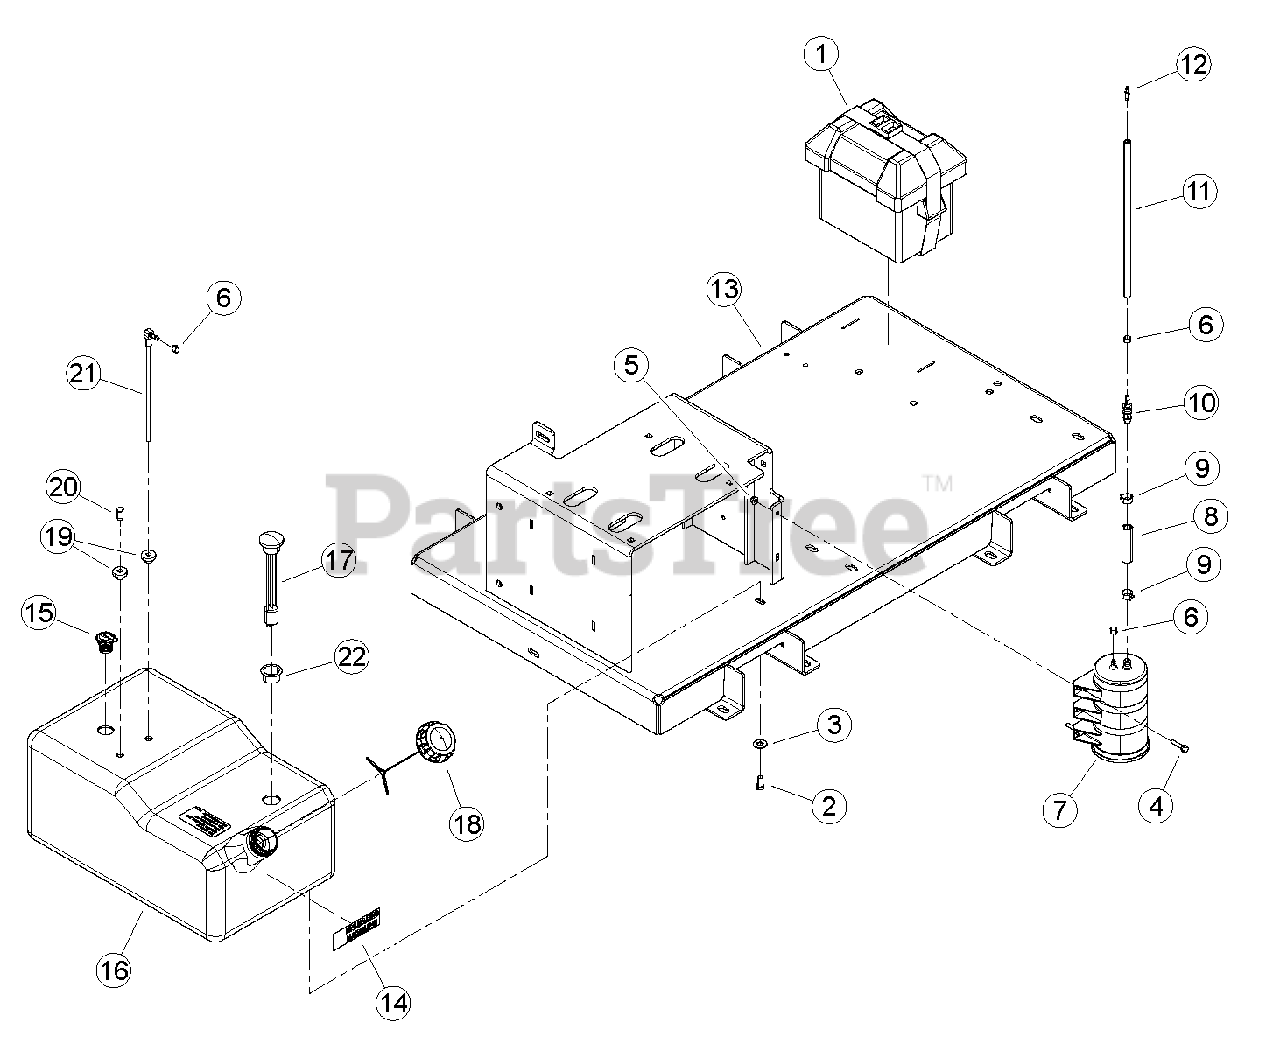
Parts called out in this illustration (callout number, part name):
1	BOX, SMALL BATTERY
2	BOLT, 3/8 X 3/4 GR5 HEX CAPSCREW ZP
3	WASHER, 3/8 FLAT
4	BOLT, 1/4 X 1-1/4 FLANGE NC
5	NUT, 1/4-20 NYLOCK FLANGE
6	CLAMP, 15/32 SPRING
7	CARBON CANISTER, 1000CC
8	HOSE, 1/2" X 3" FUEL LINE
9	CLAMP, SPRING 1/2" ID HOSE
10	FITTING, REDUCER 1/2" TO 1/4" BARB
11	HOSE, 14 INCH FUEL LINE
12	FITTING, 3/16" X 1/4" VACUUM
13	WELDMENT, BASE DL12
14	DECAL, UNLEADED GASOLINE
15	VALVE, ROLL OVER
16	TANK, ROTOMOLDED FUEL
17	GAUGE, FUEL LEVEL KELCH 100
18	CAP, NON-VENTED EPA/CARB APPROVED
19	GROMMET, TANK FITTING
20	PLUG, TANK VENT
21	FITTING, TANK FUEL PICK-UP TUBE
22	GROMMET, KELCH 100 GAUGE
